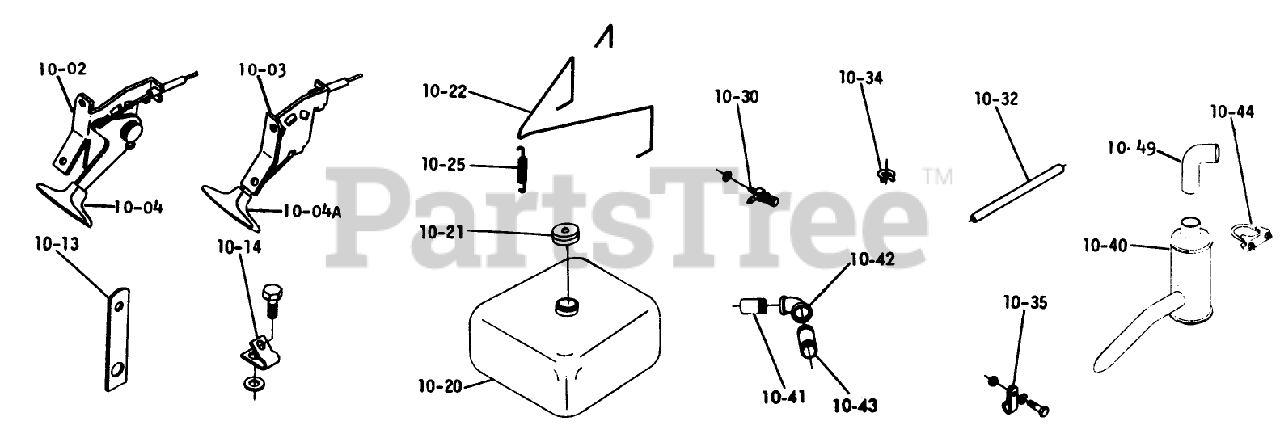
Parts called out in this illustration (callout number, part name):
10-03	THROTTLE CONTROL
10-04	KNOB-CHOKE
10-04A	KNOB-THROTTLE
10-14	THROTTLE CONTROL CLP
10-22	HOLD DOWN WIRE
10-30	VALVE-FUEL
10-40	MUFFLER
10-44	ASSY-MUFFLER CLAMP
